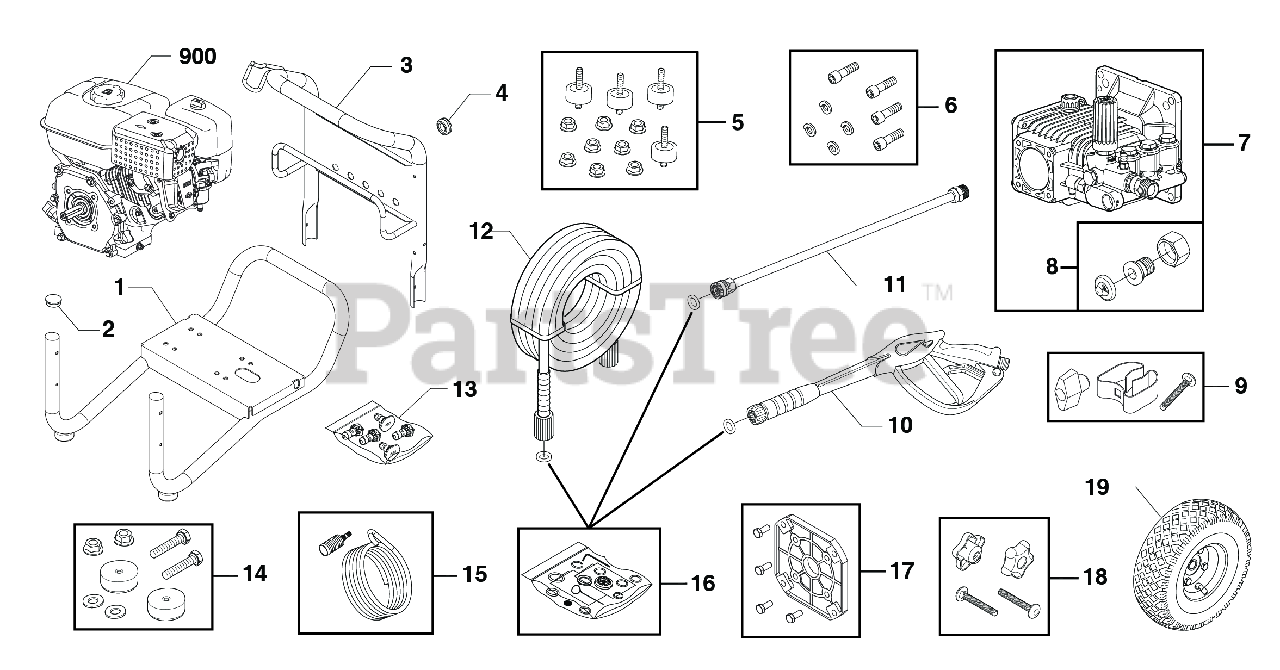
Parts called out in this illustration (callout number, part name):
4	GROMMET, Chemical Hose
5	KIT, Vibration Mount
6	KIT-HARDWARE PUMP MOUNTING
8	KIT, Connector, Hose, Garden
11	EXTENSION, QC
13	KIT-QC NOZZLES
14	KIT, Vibration Mount
15	KIT, Chem Hose & Filter
16	KIT-O-RING MAINTENANCE
17	KIT - ENGINE FLANGE
18	KIT-HARDWARE, HANDLE
19	WHEEL
